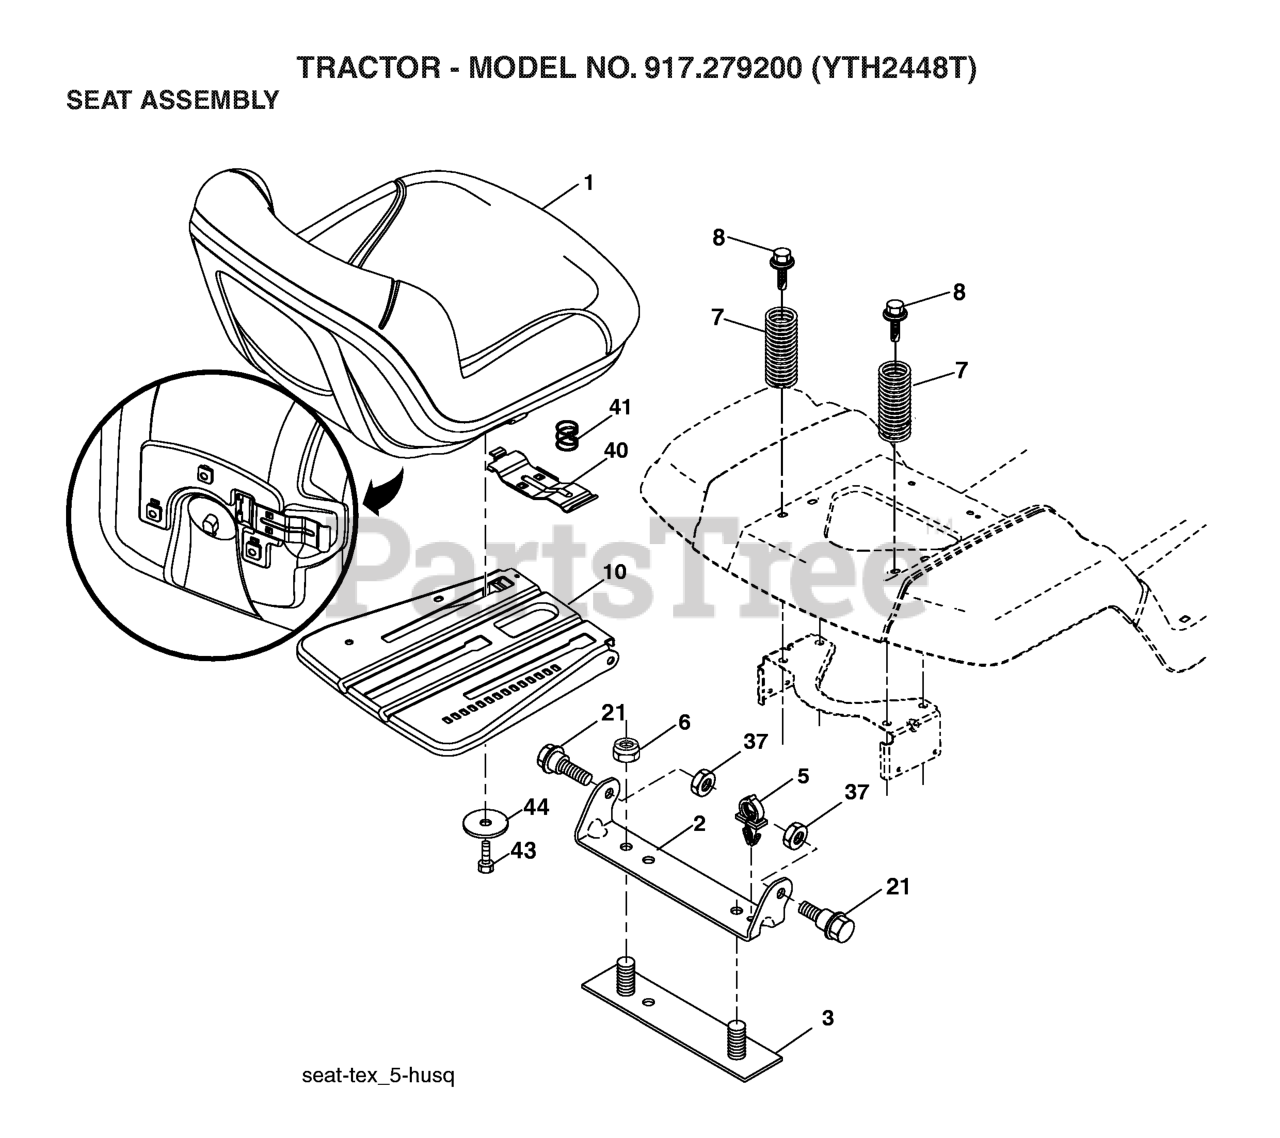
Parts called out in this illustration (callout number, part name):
1	SEAT.TH150.GRY.KB/SL.H
2	BRKT.PIVOT.FENDER
3	STRAP
6	NUT
7	SPRING COMPRESSION
8	BOLT.5/16-18UNCX3/4 W/SEMS.BLK
10	PAN.ASM.SEAT.3PT
21	BOLT.SHOULDER.5/16-18
37	NUT.71038.31-18.HEX.NYLOCK
40	HANDLE.SLIDE.SEAT.TEX.BLACK
41	SPRING.LATCH.SEAT.TEX
44	WASHER 13/32 X 2-3/8 X 12GA
